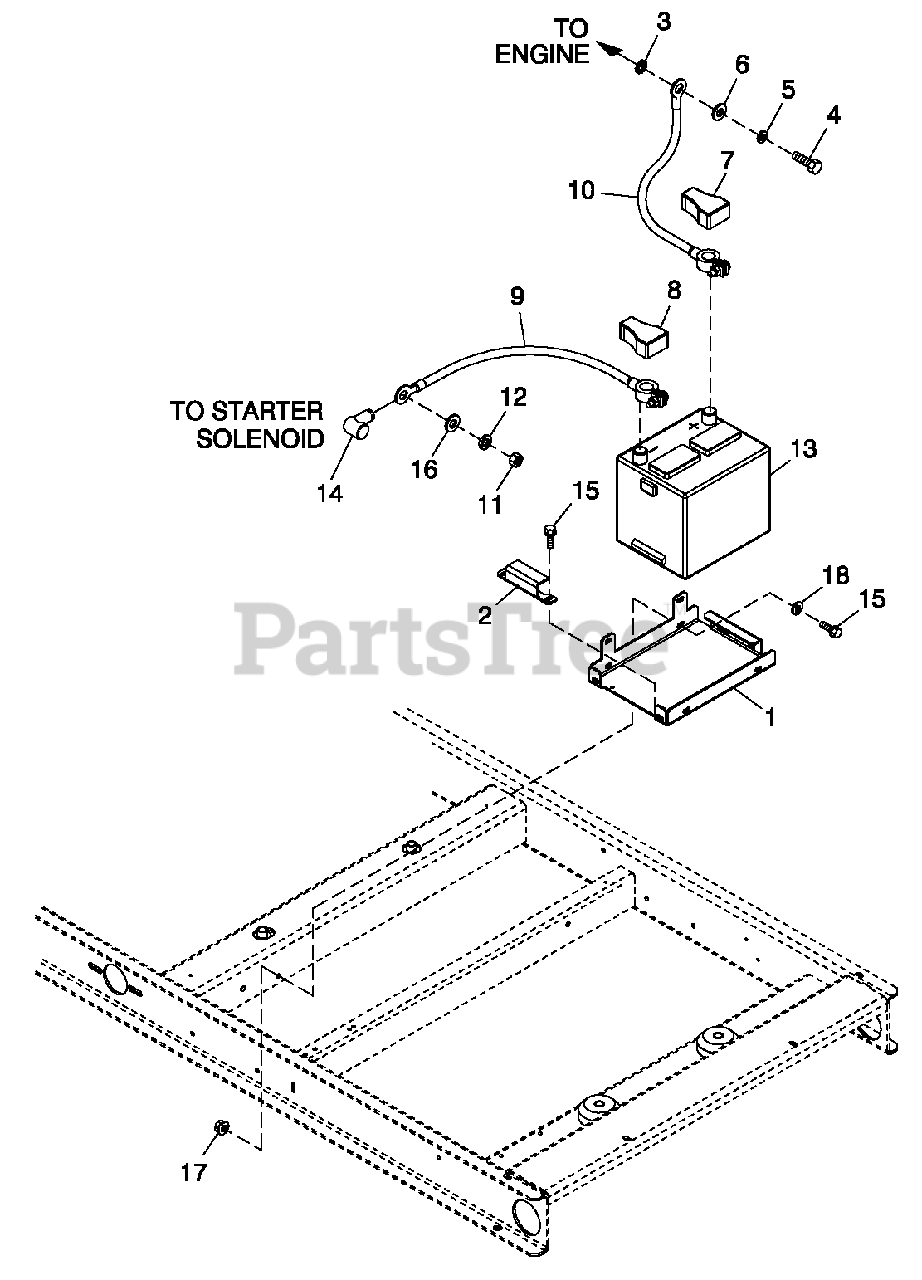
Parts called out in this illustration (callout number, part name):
1	BATTERY TRAY, C 1&C 2
2	STRAP BATTERY RETAINMENT
3	WASHER SHAKEPROOF EXT 7/16 STL
4	SCREW HHC M10-1.25 X 25 G8.8
5	WASHER LOCK M10
6	WASHER FLAT 3/8-M10 ZINC
7	BATTERY POST COVER RED +
8	BATTERY POST COVER B LACK -
9	CAB LE BATTERY B LACK #1 X 18.00
10	CAB LEBATT RED #1X18.00
11	NUTHEXM8-1.25 G8 YE L CHR
12	WASHER LOCK M8-5/16
13	BATTERY 12VDC 75-AH 26
14	BOOT CONTACTOR CAB LES
15	SCREW HHC M6-1.0X 20 C8.8
16	WASHER FLAT 5/16-M8 ZINC
17	NUT FLANGE M6-1.0 NYLOK
18	WASHER FLAT M6
